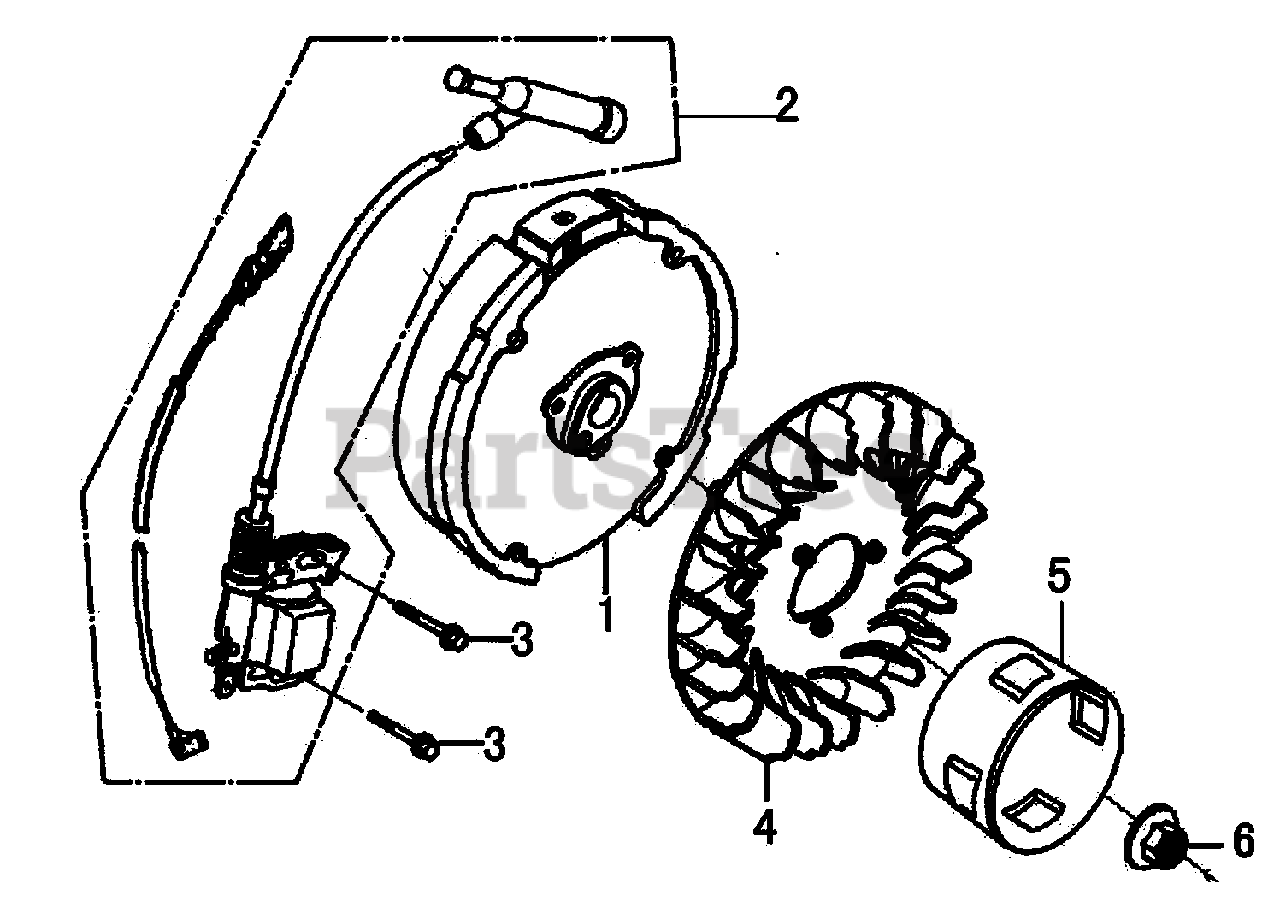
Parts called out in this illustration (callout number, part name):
2	COIL ASSY, IGNITION
3	BOLT, FLANGE 6X25
4	FAN, COOLING
5	PULLEY, STARTER
